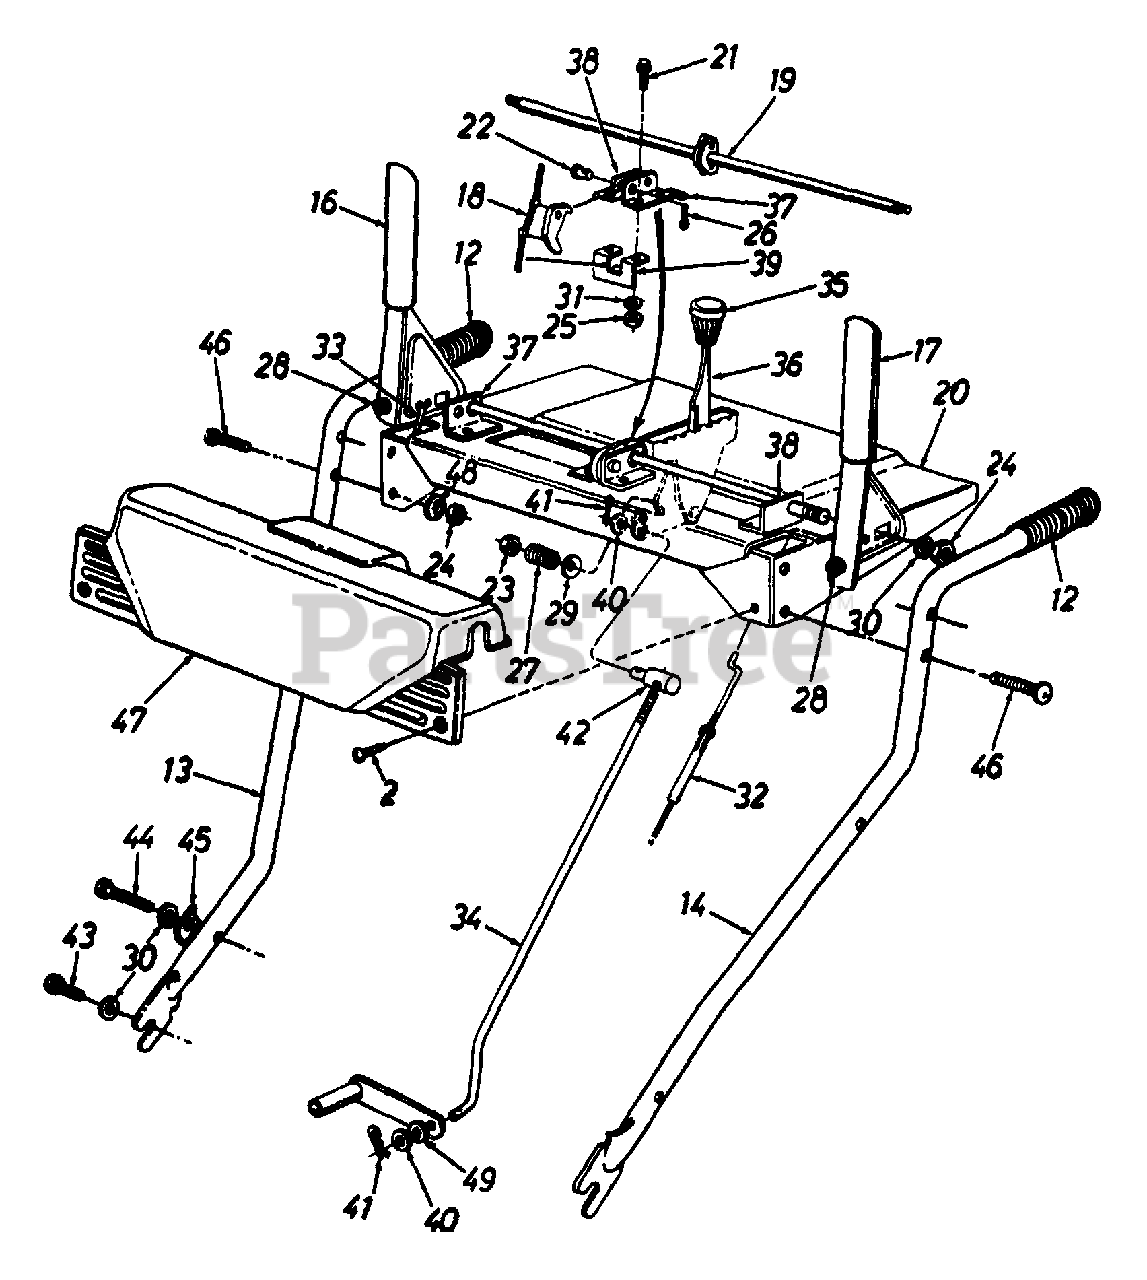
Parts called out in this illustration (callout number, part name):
2	Truss Mach. B-Tap Scr. #10 x .5
12	Grip
13	Handle - R.H.
14	Handle - L.H.
16	Engagement Handle - R.H.
17	Engagement Handle - L.H.
18	Pawl & Spring Ass'y.
19	Control Rod Cam Ass'y.
20	Handle Panel Support
21	Hex Wash. Hd. TT-Tap Scr. 1/4-20 x .5" Lg.
22	Clevis Pin .437" Dia. x .65" Lg.
23	Hex Ins. L-Nut 3/8-24 Thd.
24	Hex Nut 5/16-18 Thd.
25	Hex Nut 1/4-20 Thd.
26	Cotter Pin 3/32" Dia. x 1" Lg.
27	Compression Spring
28	Rubber Bumper
29	Bell-Wash. .38" I.D. x.88" O.D.
30	L-Wash. 5/16" I.D.
31	Spring Wash. .265" I.D.
32	Auger Clutch Cable
33	Drive Clutch Cable
34	Shift Rod
35	Shift Knob
36	Shift Handle
37	Handle Brkt.- L.H.
38	Handle Support Brkt.- R.H.
39	Spring Support Brkt.
40	Fl-Wash. .344" I.D. x.62" O.D.
41	Internal Cotter Pin 5/16" Dia.
42	Ferrule
43	Hex Bolt 5/1 6-18 x .75" Lg. (Gr. 5)
44	Hex Bolt 5/16-18 x 1.75" Lg. (Gr. 5)
45	Handle Tab
46	Curved Carr. Bolt 5/16-18 x 1.38"
47	Handle Panel
48	Bell-Wash. 5/16" I.D.
49	Spr. Wash. 5/16" I.D.
